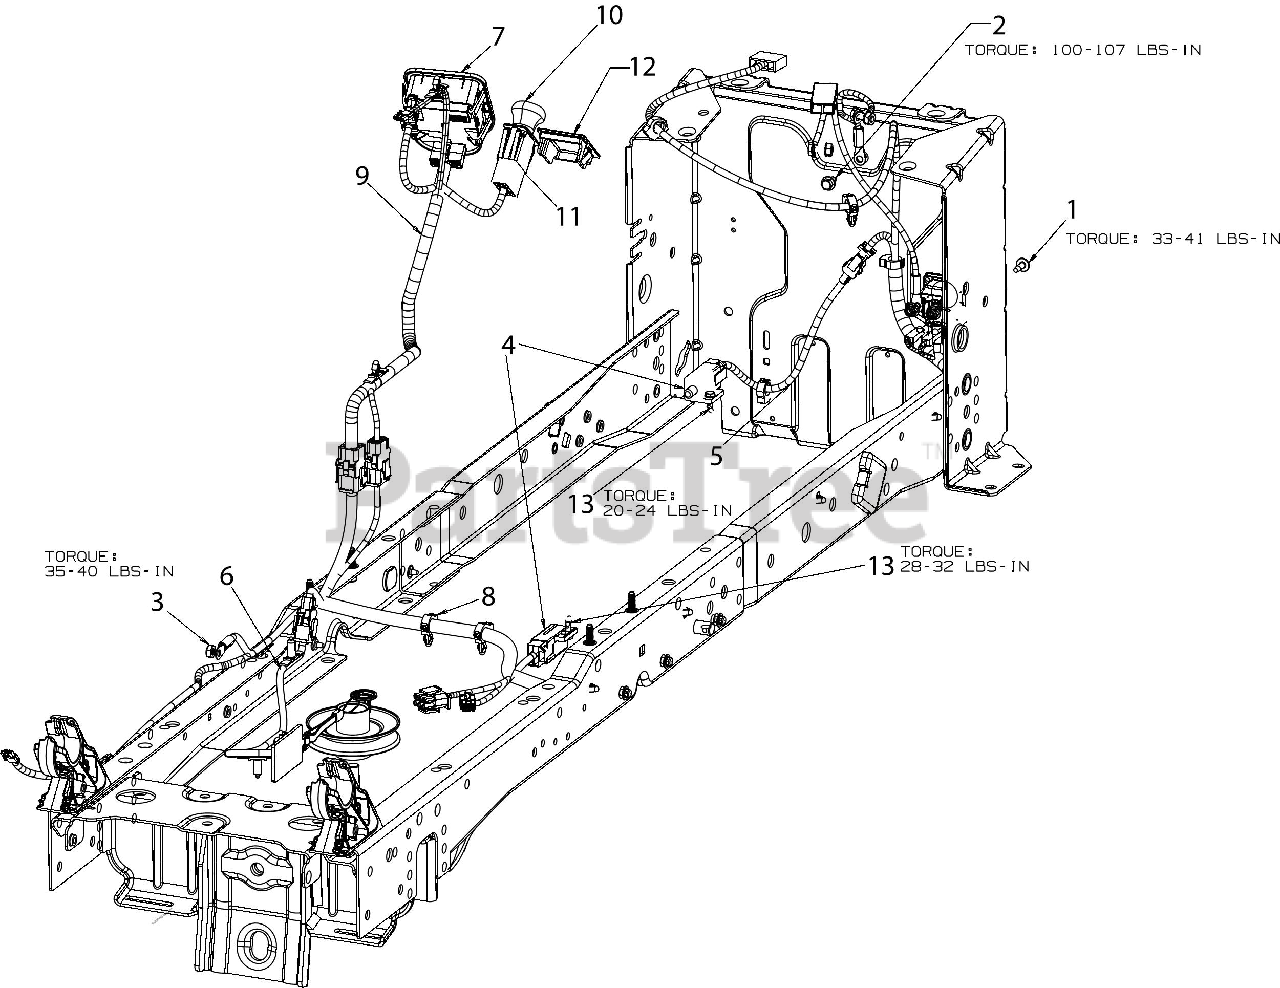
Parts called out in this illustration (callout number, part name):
1	SCREW M6-1 x .625
2	SCREW 1/4-20X.625
3	HEX NUT 1/4-20
4	INTERLOCK SWITCH (NO/NC)
5	REVERSE HARNESS
6	CLUTCH HARNESS 11"
7	MODULE-PBS/HRMTR/SVC MNDR
8	MAIN HARNESS E-PTO/PBS/EFI
9	DASH HARNESS E-PTO/PBS/EFI/RMC
10	PBS KEY
11	PTO SWITCH (YELLOW KNOB)
12	DASH HOUR METER PLUG
13	SHOULDER SCREW
